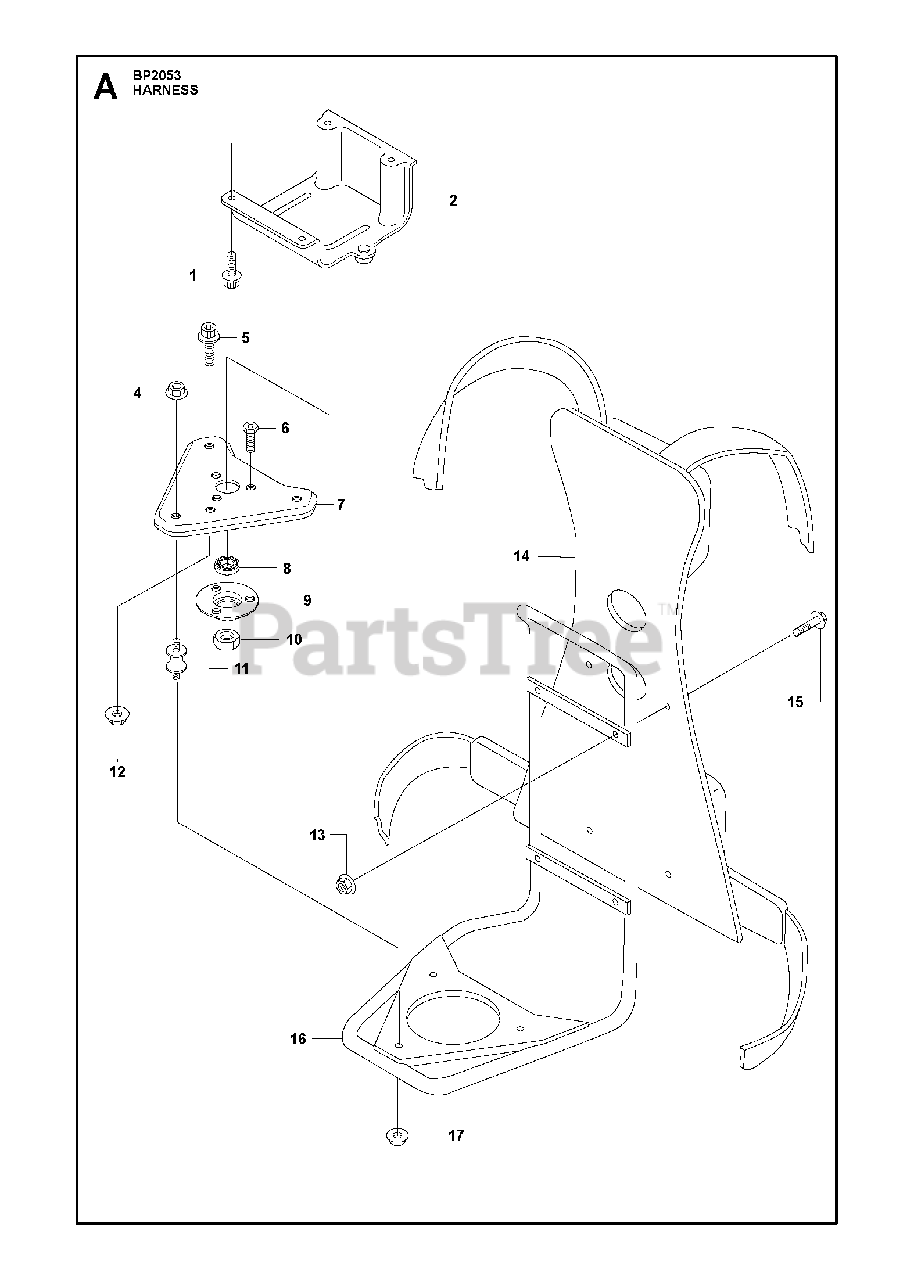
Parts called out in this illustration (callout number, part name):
4	FLANGE NUT
8	BALL BEARING
12	FLANGE NUT
17	FLANGE NUT
